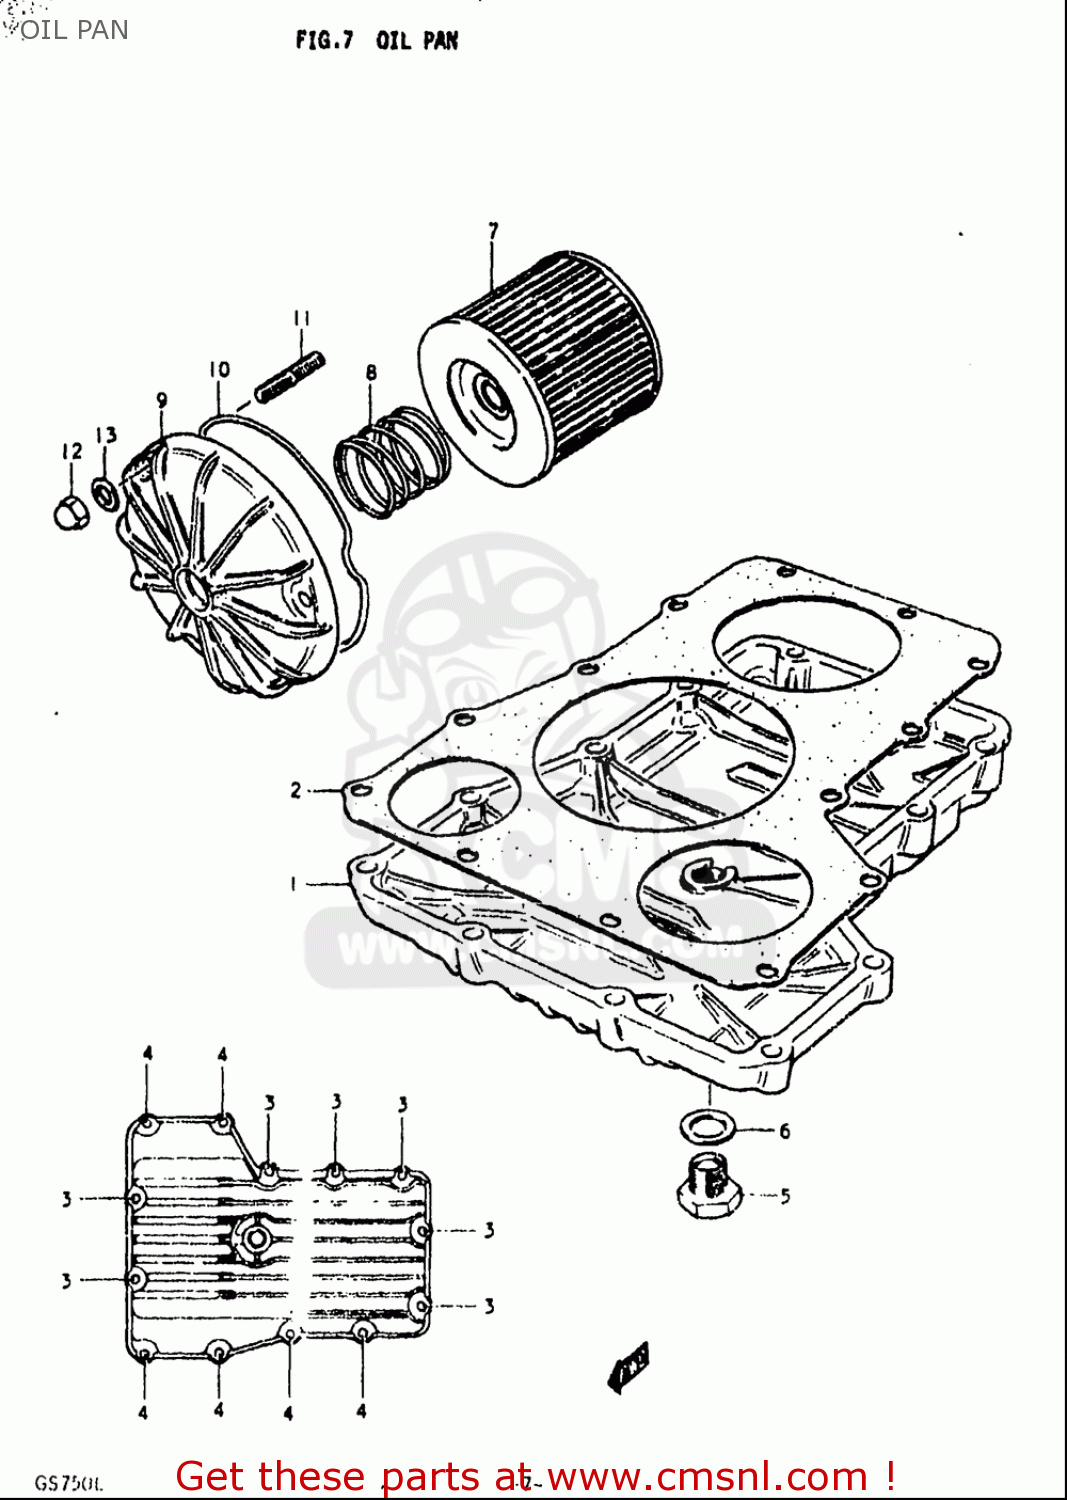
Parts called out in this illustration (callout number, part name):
2	GASKET,OIL PAN (NAS)
3	BOLT
4	BOLT
5	PLUG(MAGNETO)
6	GASKET(14X19.2X2) (NAS)
7	FILTER ASSY,ENGINE OIL
8	SPRING
10	O RING,OIL FILTER CHAMBER CAP
11	BOLT,STUD
12	NUT
13	WASHER
